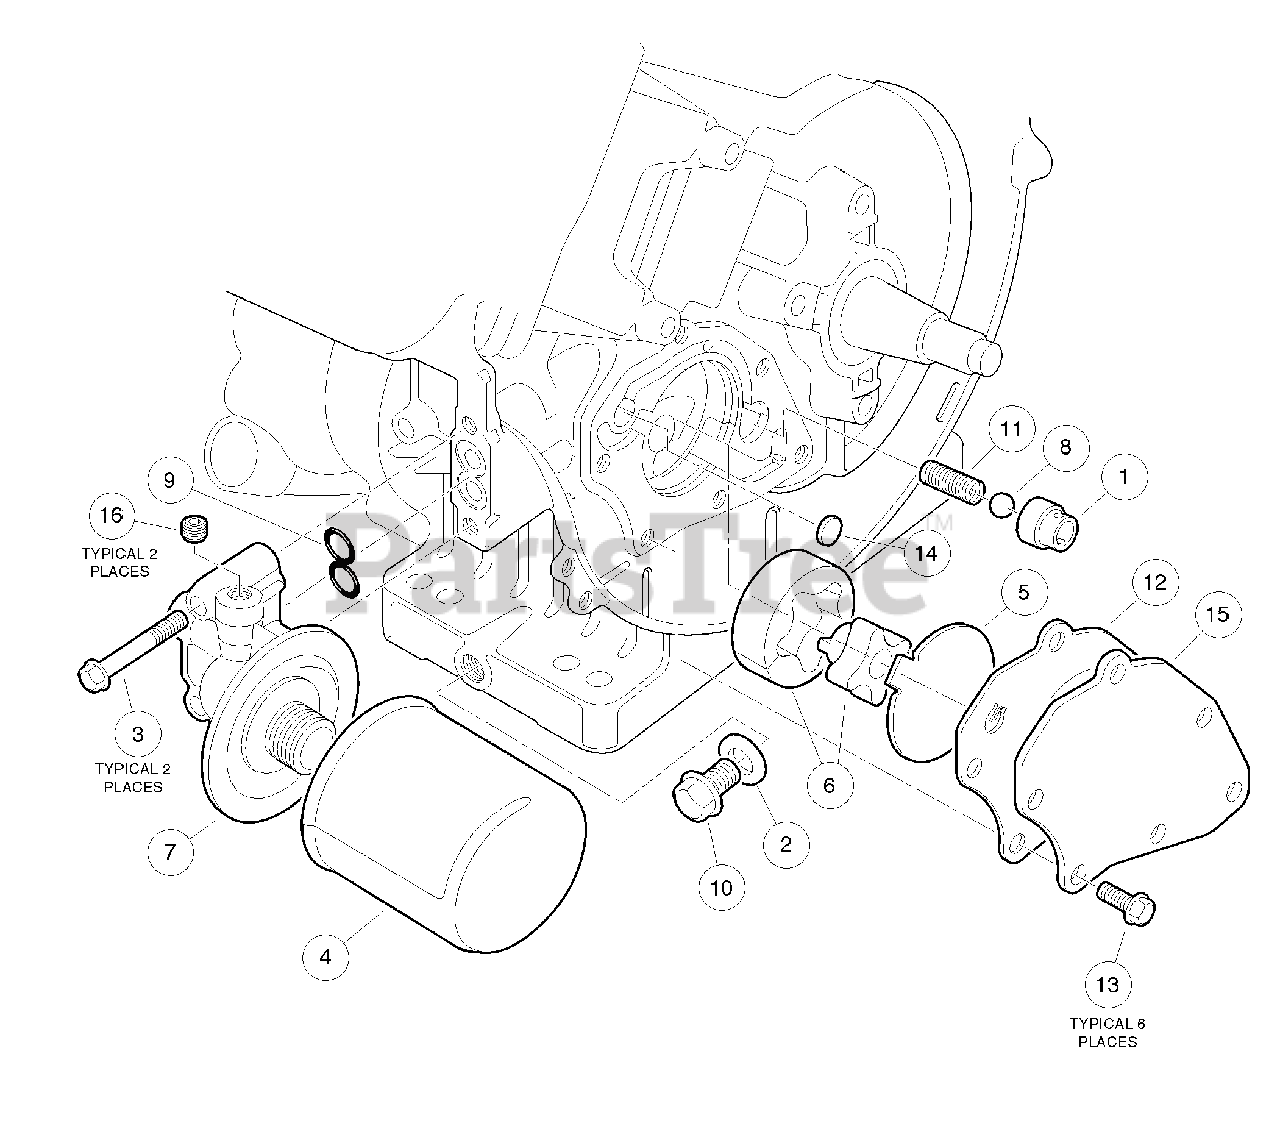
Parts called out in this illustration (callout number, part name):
1	Seat, Value Oil Press Relief
2	Gasket, Drain Plug
3	Bolt, Flange Head
4	Filter, Oil
5	Plate, Oil Pump
6	Oil Pump And Rotor
7	Bracket, Oil Filter Mount
8	Ball, Steel, Press, Relief
10	Plug, Drain
13	Bolt, Flanged
15	Cover, Pump
